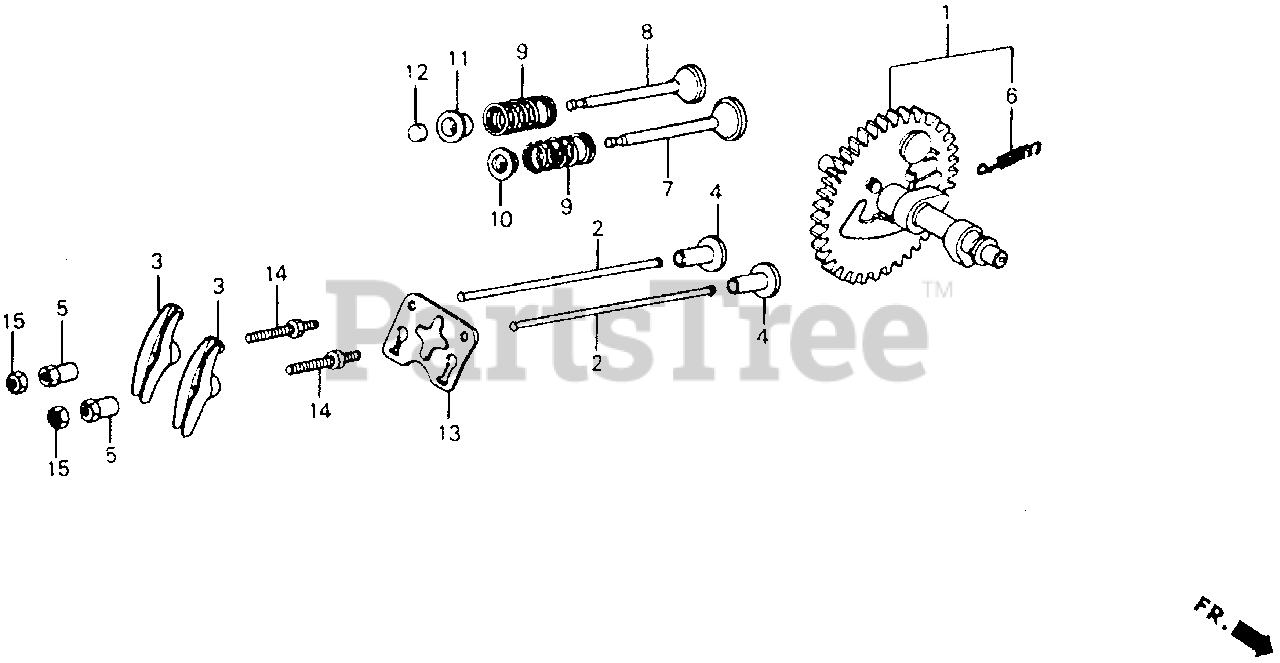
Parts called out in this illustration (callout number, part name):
1	CAMSHAFT ASSY.
2	ROD, PUSH
3	ARM, VALVE ROCKER
4	LIFTER, VALVE
5	PIVOT, ROCKER ARM
6	SPRING, WEIGHT RETURN
7	VALVE, IN.
8	VALVE, EX.
8	VALVE, EX. (STELITE)
9	SPRING, VALVE
10	RETAINER, IN. VALVE SPRING
11	RETAINER, EX. VALVE SPRING
12	ROTATOR, VALVE
13	PLATE, PUSH ROD GUIDE
14	BOLT, PIVOT (8MM)
15	NUT, PIVOT ADJ.
